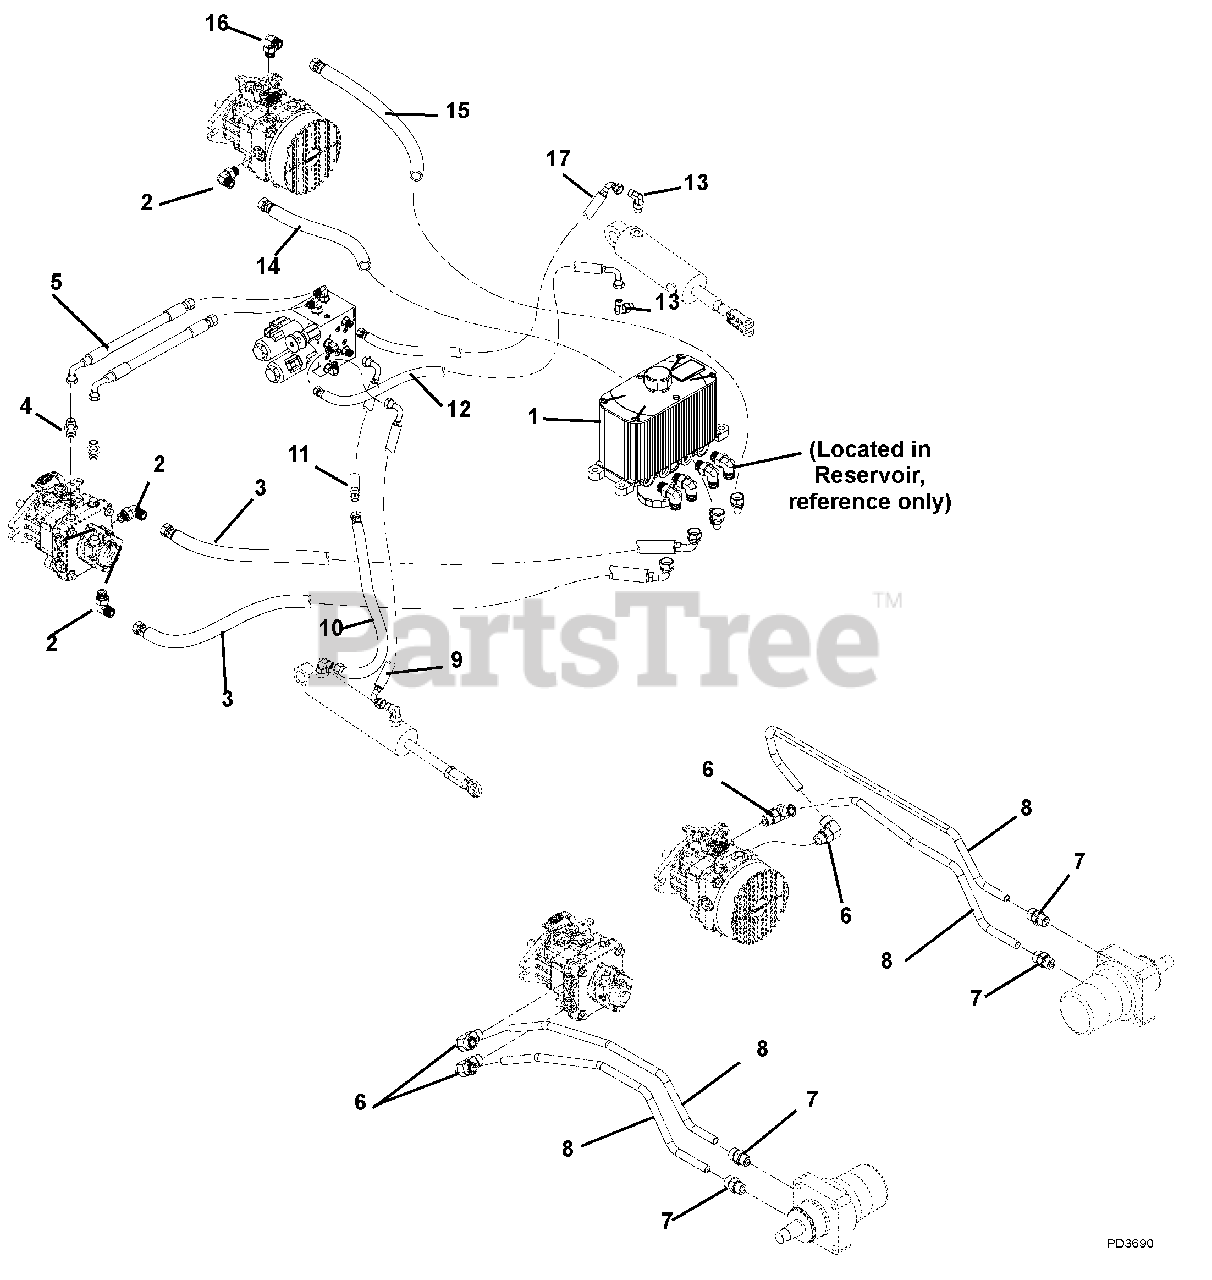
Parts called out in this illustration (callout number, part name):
1	Tank, Hydraulic Reservoir/Filter
2	Fitting, Hydraulic 90 Elbow M8F-M8O 8 C5OLO-Steel
3	Hose, Hydraulic .50-15-0K F08F0-F08F9
4	Fitting, Hydraulic
5	Hose, Hydraulic
6	Fitting, Hydraulic 90 M10F-M8O
7	Fitting, Hydraulic Straight M10O-M10F
8	Hose, Hydraulic .50-25-2K F10F0-F10F0
9	Hose, Hydraulic .25-39-2K F04F0-F04F0
10	Hose, Hydraulic .25-16-2K F04F0-F04F9
11	Hose, Hydraulic .25-20-2K F04F9-F04F9
12	Hose, Hydraulic .25-21-2K F04F0-F04F9
13	Adapter, Hydraulic Fitting 90 M4F-M6O 4-6 C5OLO
14	Hose, Hydraulic .5-17.25-0K F8F9-F8F9
15	Hose, Hydraulic .5-17.25-0K F8F9-F8F9
16	Adapter, Face Seal 8 x 8 .50 O-Ring
17	Hose, Hydraulic .25-16-2K F04F9-F04F0
NS	Filter, Hydraulic
